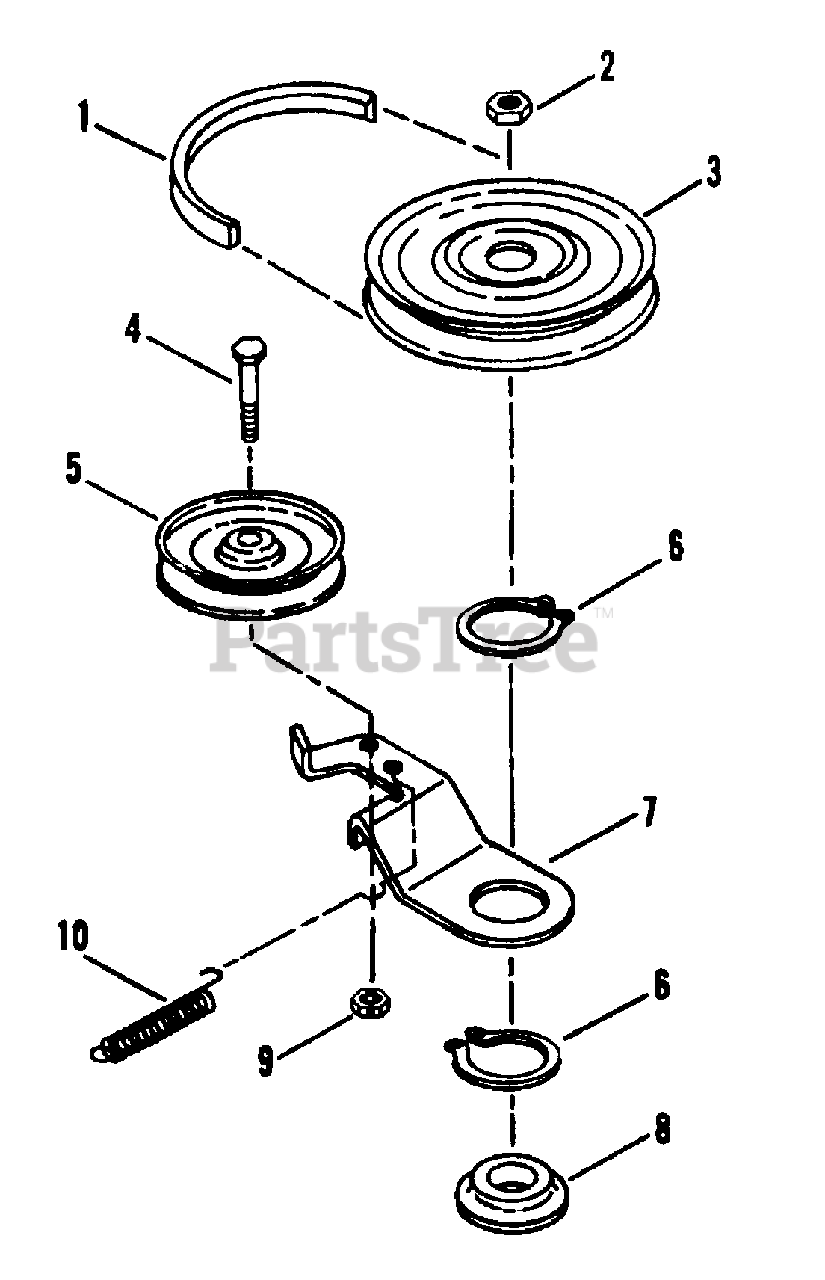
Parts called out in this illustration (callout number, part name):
1	BELT, Drive
2	NUT, 3/4-16 Hex Jam
3	PULLEY, Drive
4	SCREW, 3/8-16 x 2" Hex Head Cap, Grade 5
5	PULLEY, Idler
6	RING, 2" External Retaining
7	ARM, Brake
8	WASHER, Spindle
9	NUT, 3/8-16 Hex Center Lock, Grade 5 or B
10	SPRING, Idler
